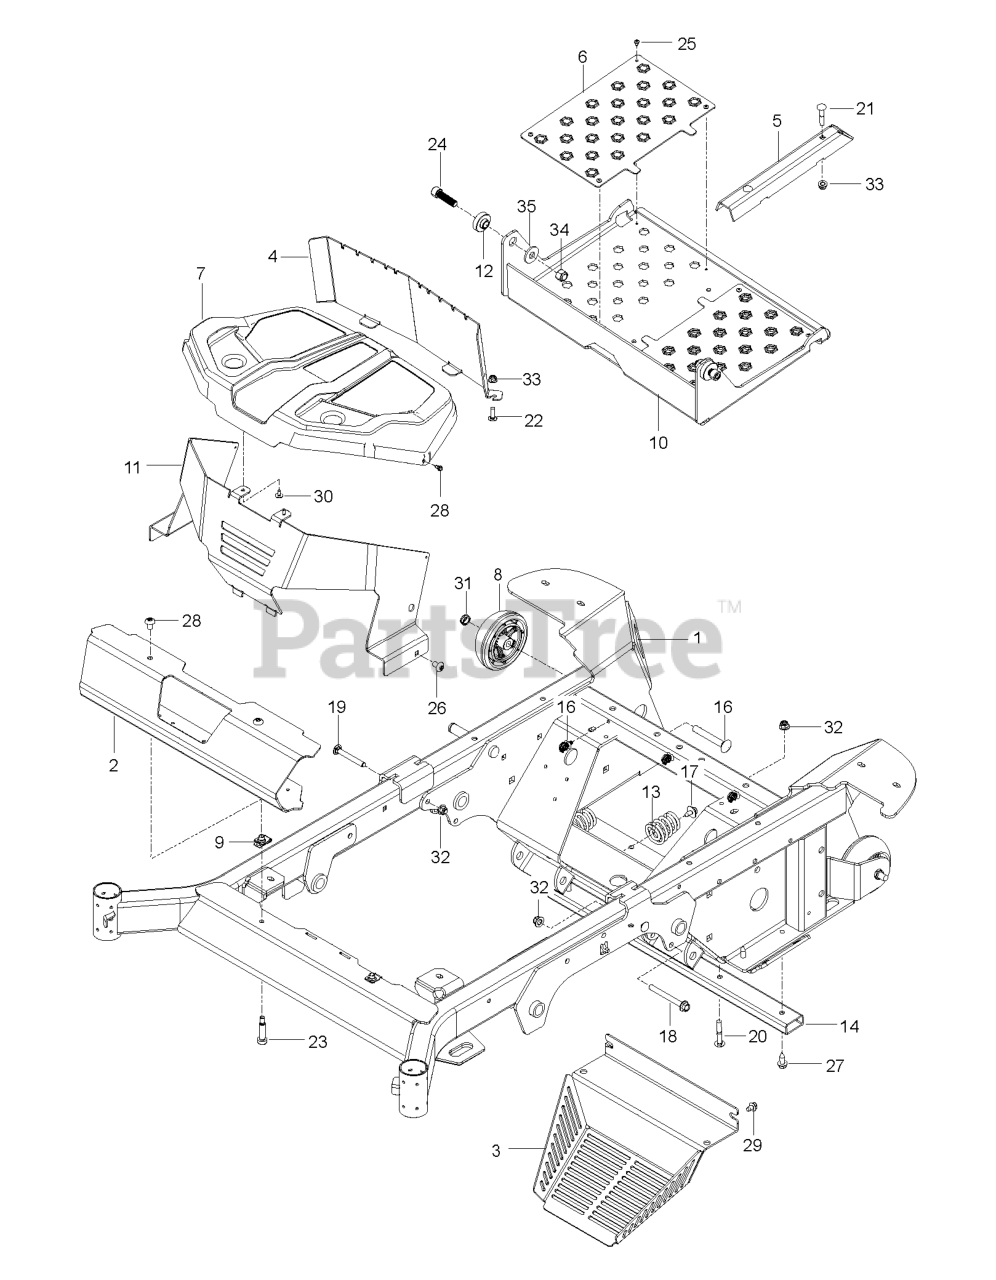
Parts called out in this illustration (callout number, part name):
1	CHASSIS.WELDMENT.VZ.MS668
2	COVER FRONT CROSSMEMBER VZ
3	COVER PTO VZ MS668 ORANGE
4	BAFFLE PLATE PUMP X431 E-COAT
5	BRACKET ANGLE OPERATOR STAND V
6	FOOTPLATE OPERATOR STAND VZ MS
7	SHROUD PUMP
8	WHEEL.GAUGE.RALLY.NARROW
9	SCREW.BUTTON.HEAD.TORX.3/8-161
10	PLATE OPERATOR STAND VZ MS498
11	PUMP SHROUD
12	SPACER.IDLER.METAL.POWDER
13	SPRING.COMPRESS.SEAT.TAPERED
14	TUBE SKIDPLATE
15	CABLE, 1/4 BLACK FIR TREE
16	BOLT 1/2 - 13 X 3.5 CARRIAGE
17	BOLT.5/16-18UNCX3/4 W/SEMS.BLK
18	HHFS 3/8-16 X 3.5 GD 5 ZD
19	3/8-16 X 3` CARR BOLT
20	BOLT CARRIAGE
21	BOLT, CARRIAGE
23	BOLT HEXAGON SOCKET HEAD, SHOU
24	BOLT 1/2-13 X 1.75 CAP
25	SCREW 10-24 X .325 TORX PAN
27	SCREW 3/8-16X1
28	SCREW, HEX HEAD, TAPPING
29	SCR 5/16-18 X 1/2 SELFTAP ZN
30	SCREW.#10 X 0.500
31	NUT 1/2-13 HEX JM NYL
32	NUT 3/8-16 HEX FLG NYLOC ZD
33	5/16-18 NYLOC FLANGE NUT
34	NUT 1/2-13 HEX NYLOC ZD
35	WASH USS FLAT 1/2
